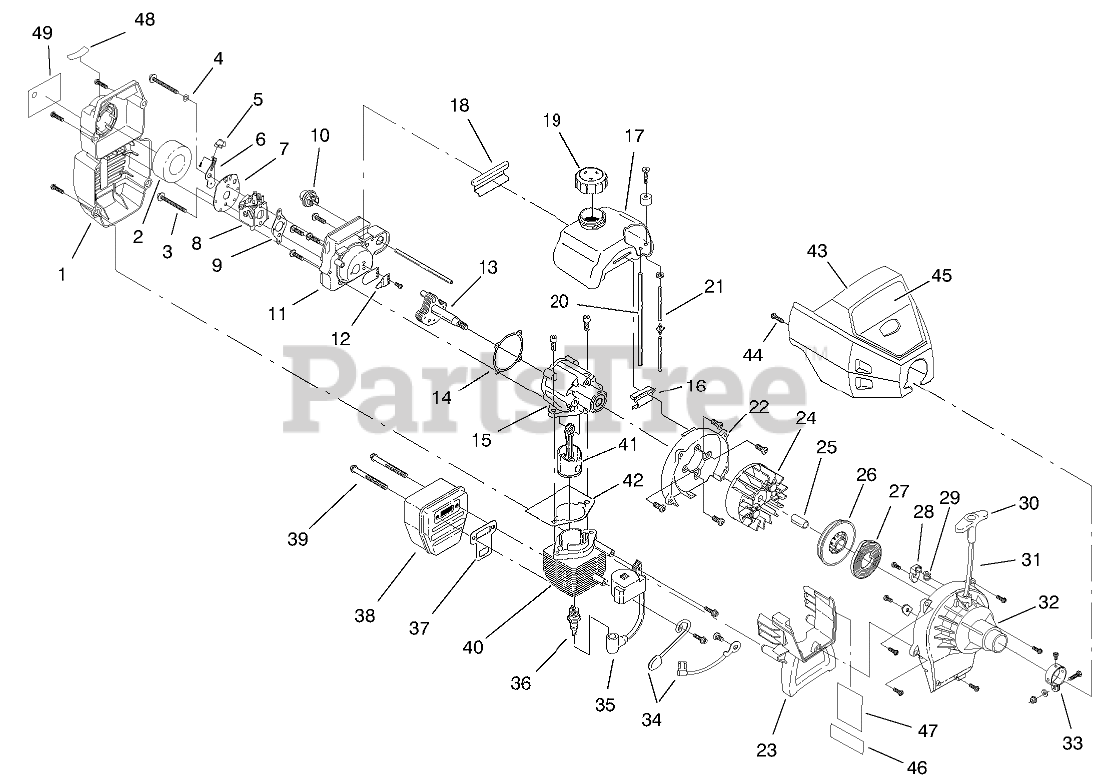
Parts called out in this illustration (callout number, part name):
1	Cover ASM (Includes Ref #2)
2	FILTER - AIR CLEANER
3	ASSEMBLY - MOUNTING BOLT
4	WAVEY WASHER
5	Choke Lever ASM (Includes Ref #6)
6	CHOKE KNOB & SCREW (SERVICE)
7	Choke Lever & Plate (Includes Ref #5)
8	ASM-CARBURETOR MOUNT
9	CARBURETOR GASKET(10 PER PACK)
10	PRIMER & HOSE ASM
11	CARB. MOUNT ASM.
12	REED ASSEMBLY
13	Power Shaft ASM
14	CARB MT GASKET (10-PK)
15	Crank Case ASM (Includes Ref #13)
16	FRONT MOUNTING PAD
17	Fuel Tank ASM (Includes Ref #19-21)
18	REAR MOUNTING PAD
19	FUEL TANK CAP
20	ASSEMBLY - RETURN LINE
21	FUEL LINE ASM
22	SHROUD ASM
23	SHROUD EXTENSION (SERVICE)
24	FLYWHEEL ASSEMBLY
25	SQUARE DRIVE NUT
26	RECOIL PULLEY ASM
27	RECOIL SPRING
28	PULLEY RETAINER ASSEMBLY
29	ROPE GUIDE
30	HANDLE - STARTER
32	ASM-HOUSING STARTER (SERVICE)
33	CLAMP ASM - UPPER
34	Ground Tab
35	MODULE ASM
36	SPARK PLUG
37	GASKET-EXHAUST (SERVICE)
38	Muffler ASM (Includes Ref #39)
39	MUFFLER MTG BOLT ASM
40	CYLINDER ASM
41	PISTON & ROD ASM
42	CYLINDER GASKET
43	COVER - ENGINE
44	Screw
45	DECAL - ENGINE COVER
46	Decal-Warning
47	DECAL-CARB (SERVICE)
48	DECAL-CHOKE POSITION (SERVICE)
49	DECAL-FUEL & OIL MIX (SERVICE)
